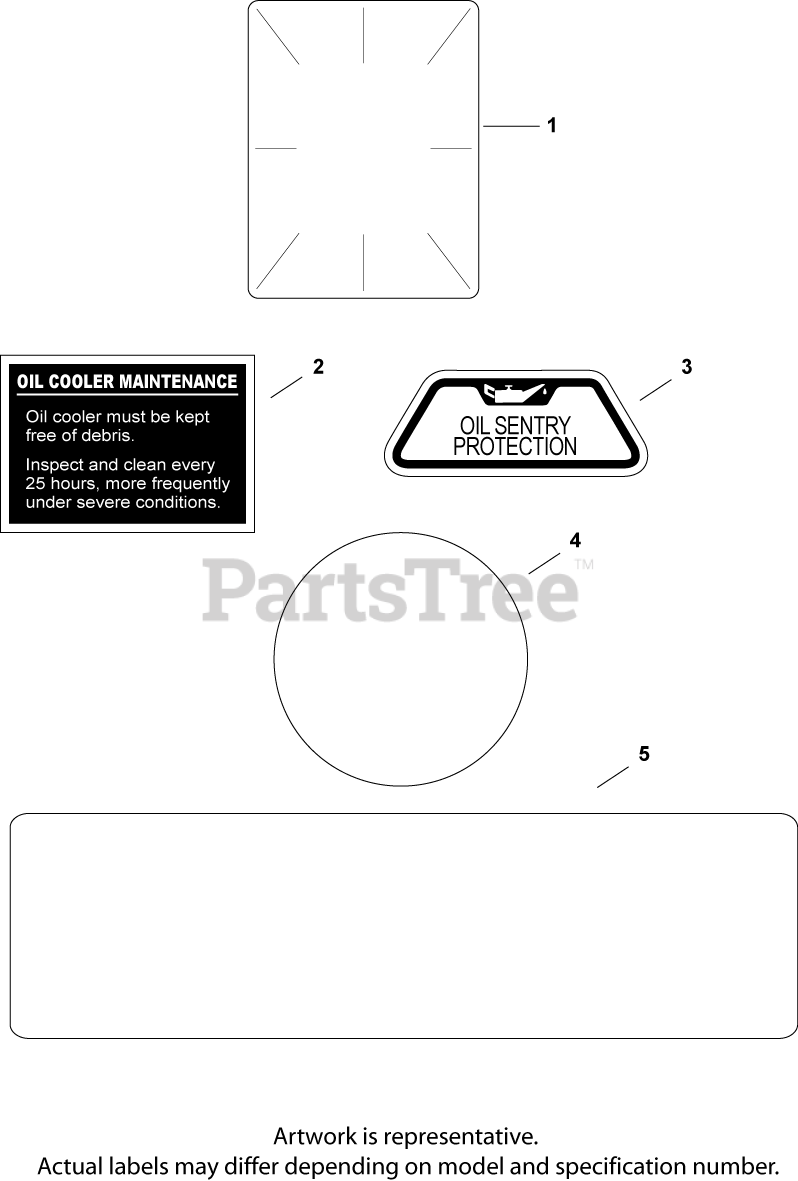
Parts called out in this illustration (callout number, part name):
1	DECAL, CLEAR LAMINATE USE 25 113 70-S
2	DECAL, OIL SENTRY - (#DSC)
3	DECAL, OIL COOLER - (#DSC)
4	LABEL, (ROUND KOHLER GOLD)-USE 24 113 18
5	DECAL, 25 HP
